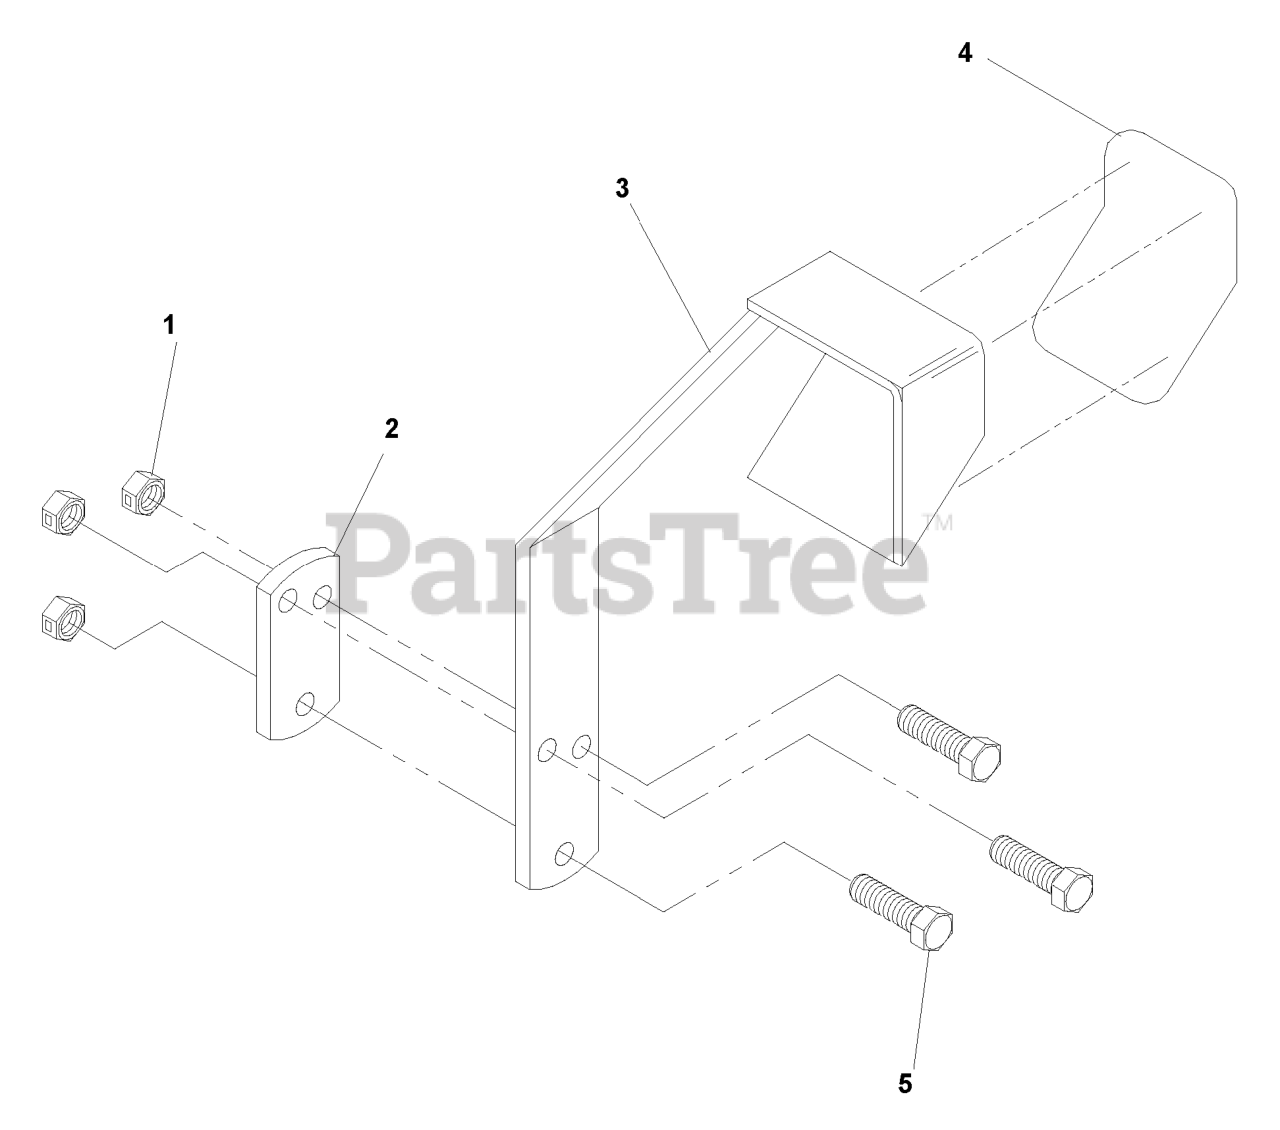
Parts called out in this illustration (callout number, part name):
1	NUT 3/8-16 NYLOC
2	TIGHTENING PLATE BLK
3	LIFT PEDAL BLK
4	ANTI-SKID PAD
5	HCS 3/8C X 1 1/2
